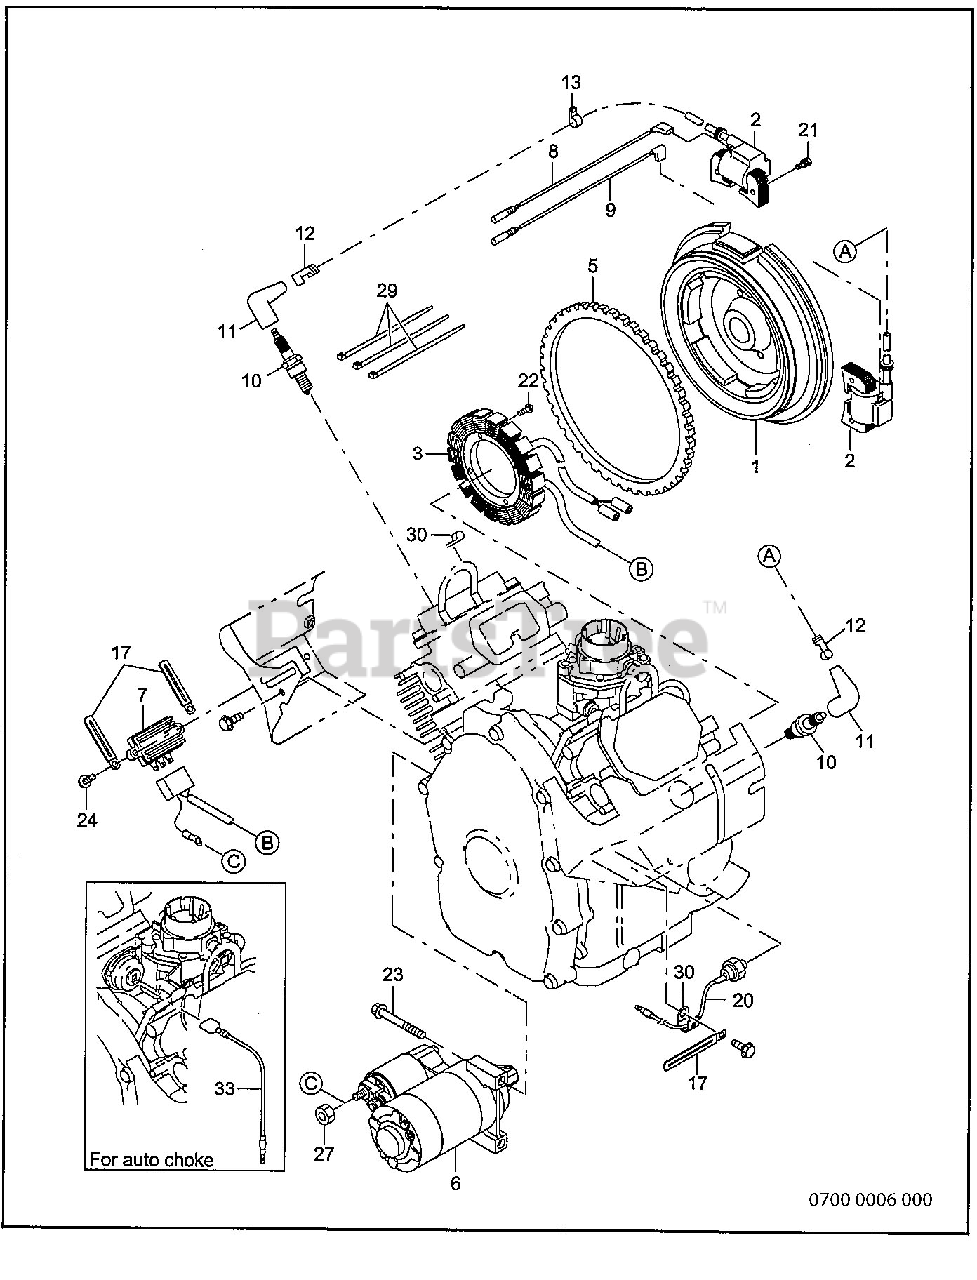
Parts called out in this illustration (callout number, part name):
2	IGNITION COIL ASSY
3	CHARGE COIL ASSY
6	STARTING MOTOR ASSY
7	REGULATOR ASSY
10	SPARK PLUG (BPR6ES)
11	SPARK PLUG CAP
20	WIRE ASSY, oil pressure switch
21	BOLT and WASHER ASSY
22	SCREW and WASHER ASSY
23	FLANGE BOLT
24	FLANGE BOLT
33	WIRE 6 ASSY
